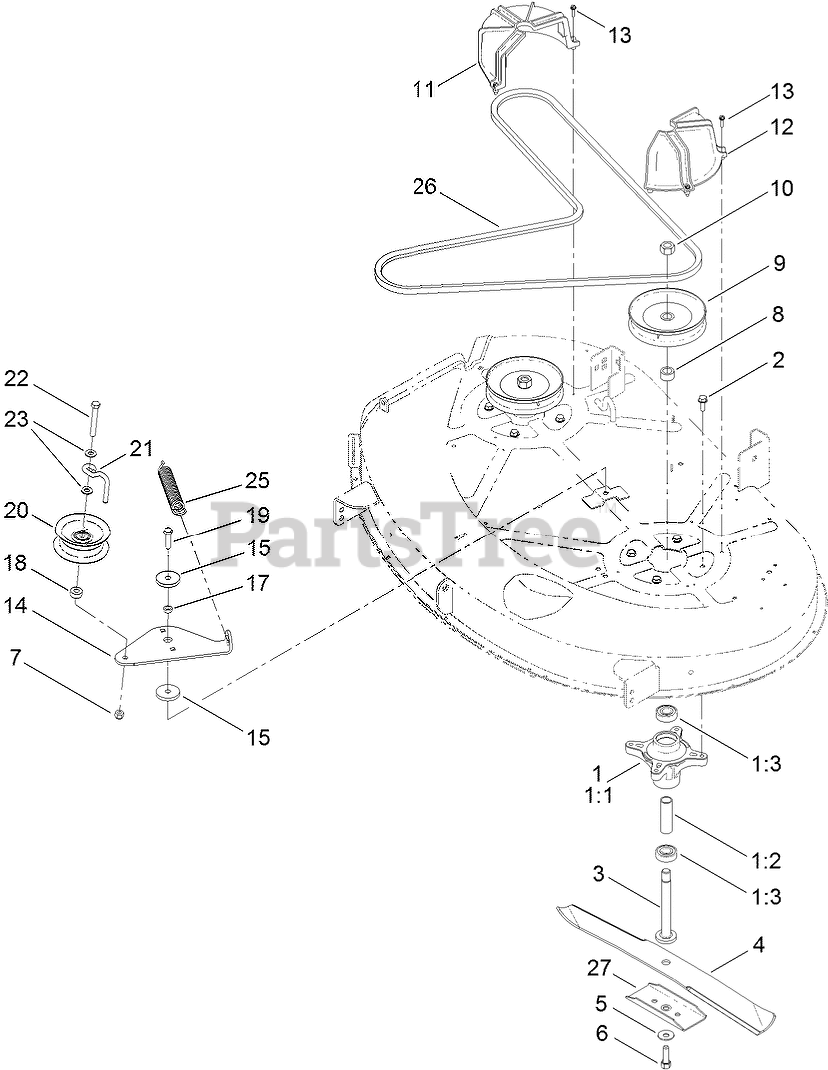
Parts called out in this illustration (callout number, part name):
1	SPINDLE ASM
1:1	SPINDLE
1:2	SPACER
1:3	BEARING-BALL
2	SCREW-TAPTITE
3	SHAFT-SPINDLE
5	WASHER-BELLEVILLE
6	SCREW-HH
7	NUT-HF, NI
8	SPACER-PULLEY
9	PULLEY
10	NUT-HEX
11	GUIDE-BELT, RH
12	GUIDE-BELT, LH
13	SCREW-SHWH, THREAD FORMING
14	ARM-IDLER
15	WASHER-PLAIN
17	SPACER
18	SPACER
19	SCREW-HH
20	PULLEY-IDLER, FLAT
21	GUIDE-IDLER, BELT
22	SCREW-HH
23	WASHER-FLAT
25	SPRING-EXTENSION
26	BELT-V
27	STIFFENER-BLADE
